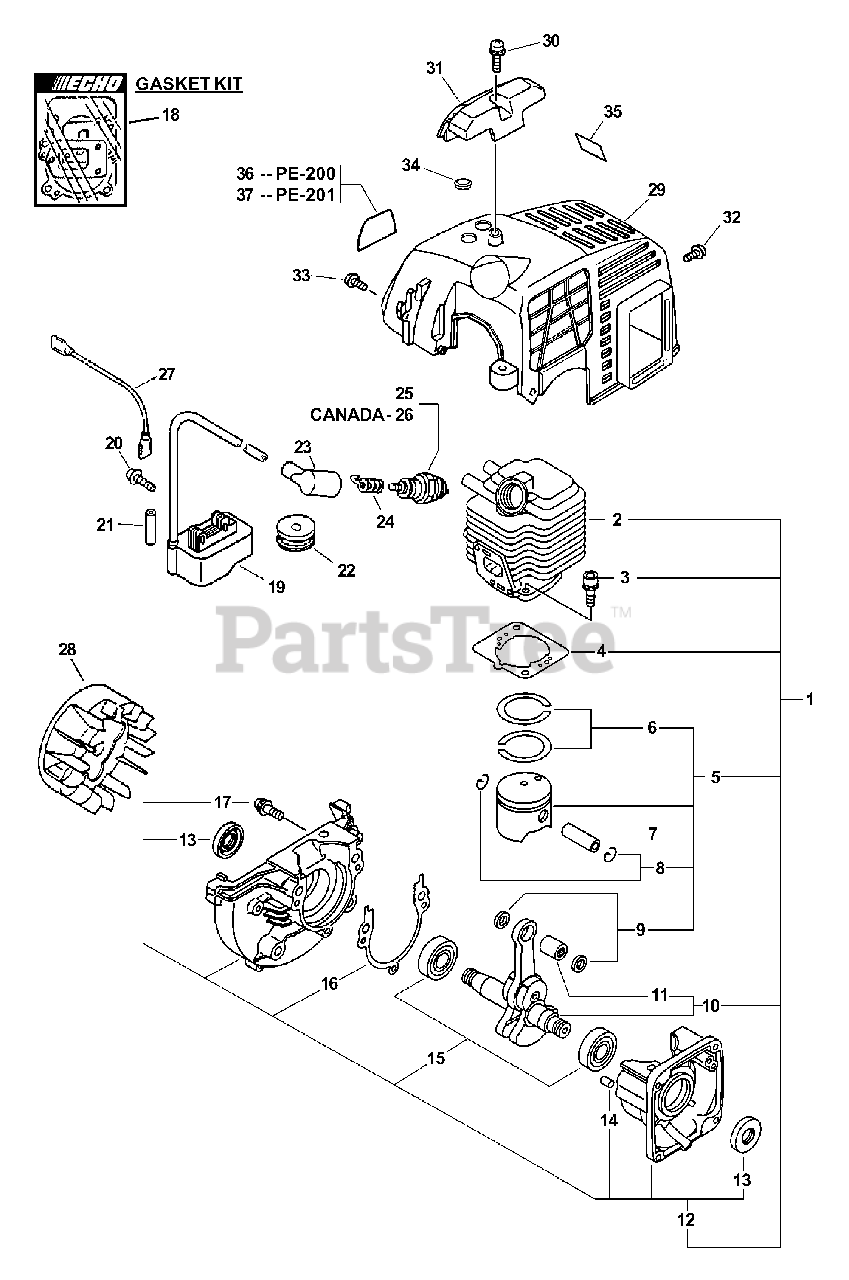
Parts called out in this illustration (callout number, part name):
1	SHORT BLOCK -- SB1065
2	CYLINDER
3	SCREW - 5X22
4	GASKET, CYLINDER
5	PISTON KIT
6	RING, PISTON
7	PIN, PISTON
8	RING, RETAINING
9	SPACER, PISTON
10	CRANKSHAFT ASSY
11	BEARING, NEEDLE - 8
12	CRANKCASE KIT
13	SEAL, OIL
14	PIN - LOCATING
15	BEARING, BALL - 6201
16	GASKET, CRANKCASE
17	SCREW - 5X28
18	GASKET KIT
19	COIL, IGNITION
20	SCREW - 4X20
21	TUBE, INSULATOR
22	GROMMET
23	CAP, SPARK PLUG
24	TERMINAL, SPARK PLUG CAP
25	SPARK PLUG -- BPM-8Y
26	SPARK PLUG -- BPMR-8Y
27	LEAD - GROUND
28	FLYWHEEL
29	COVER, ENGINE
30	SCREW - 5X16 -- TAPPING
31	GUARD - TOP
32	SCREW - 4X8
33	SCREW - 4X12 -- TAPPING
35	LABEL - HOT SURFACE
36	LABEL - MODEL PE-200
37	LABEL - MODEL PE-201
